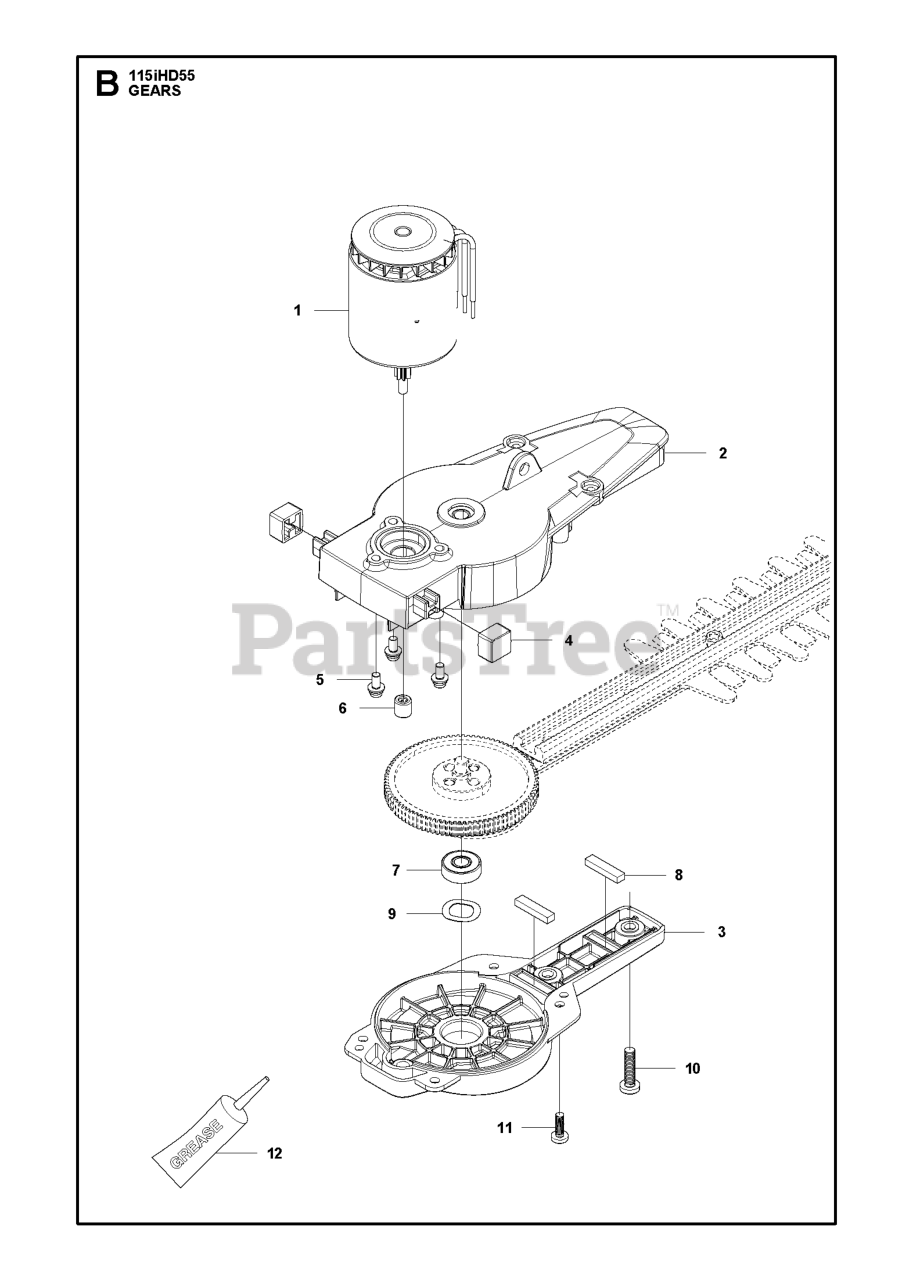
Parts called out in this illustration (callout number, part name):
1	MOTOR BLDC 115IHD55
3	COVER GEAR BOX
4	SHOCK ABSORBING
6	NEEDLE BEARING
7	BALL BEARING
8	PAD DUSTPROOF
9	SPRING WASHER
10	SCREW M5X20
11	SCREW M4X12
12	GREASE 20G HEDGE TRIMMER GEAR
